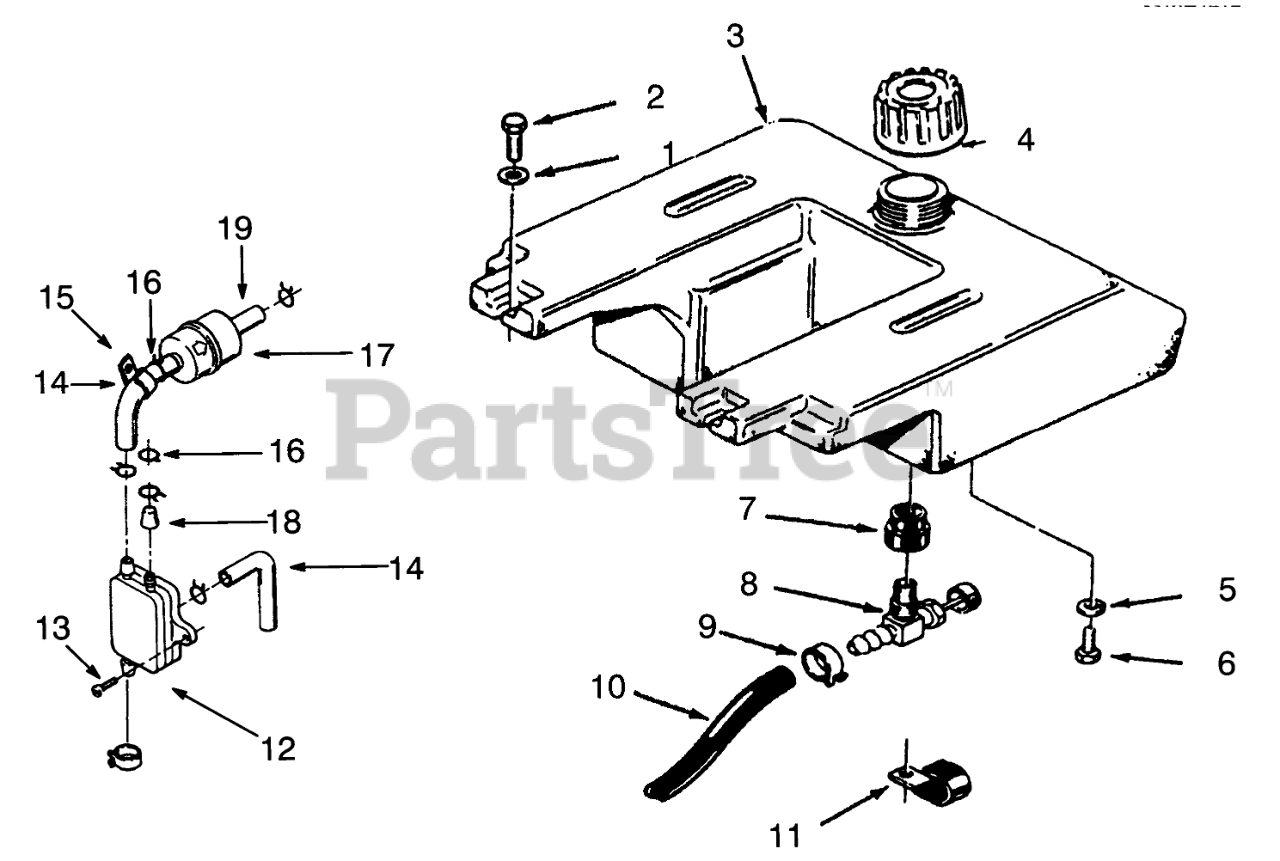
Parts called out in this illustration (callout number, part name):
1	WASHER-FLAT
2	Bolt
3	Tank-Fuel (Incl. Ref. #5 & 7)
4	GAS CAP ASM
5	WASHER-LOCK
6	SCREW-HH
7	BUSHING
8	VALVE-FUEL
9	Clamp
10	Fuel Line 62
11	Clamp
12	PUMP-FUEL
13	SCREW-TAPPING PAN HD
14	Hose
15	Clip
16	CLAMP-HOSE
17	Filter-Fuel
18	CAP-FUEL OUTLET
19	FUEL HOSE
